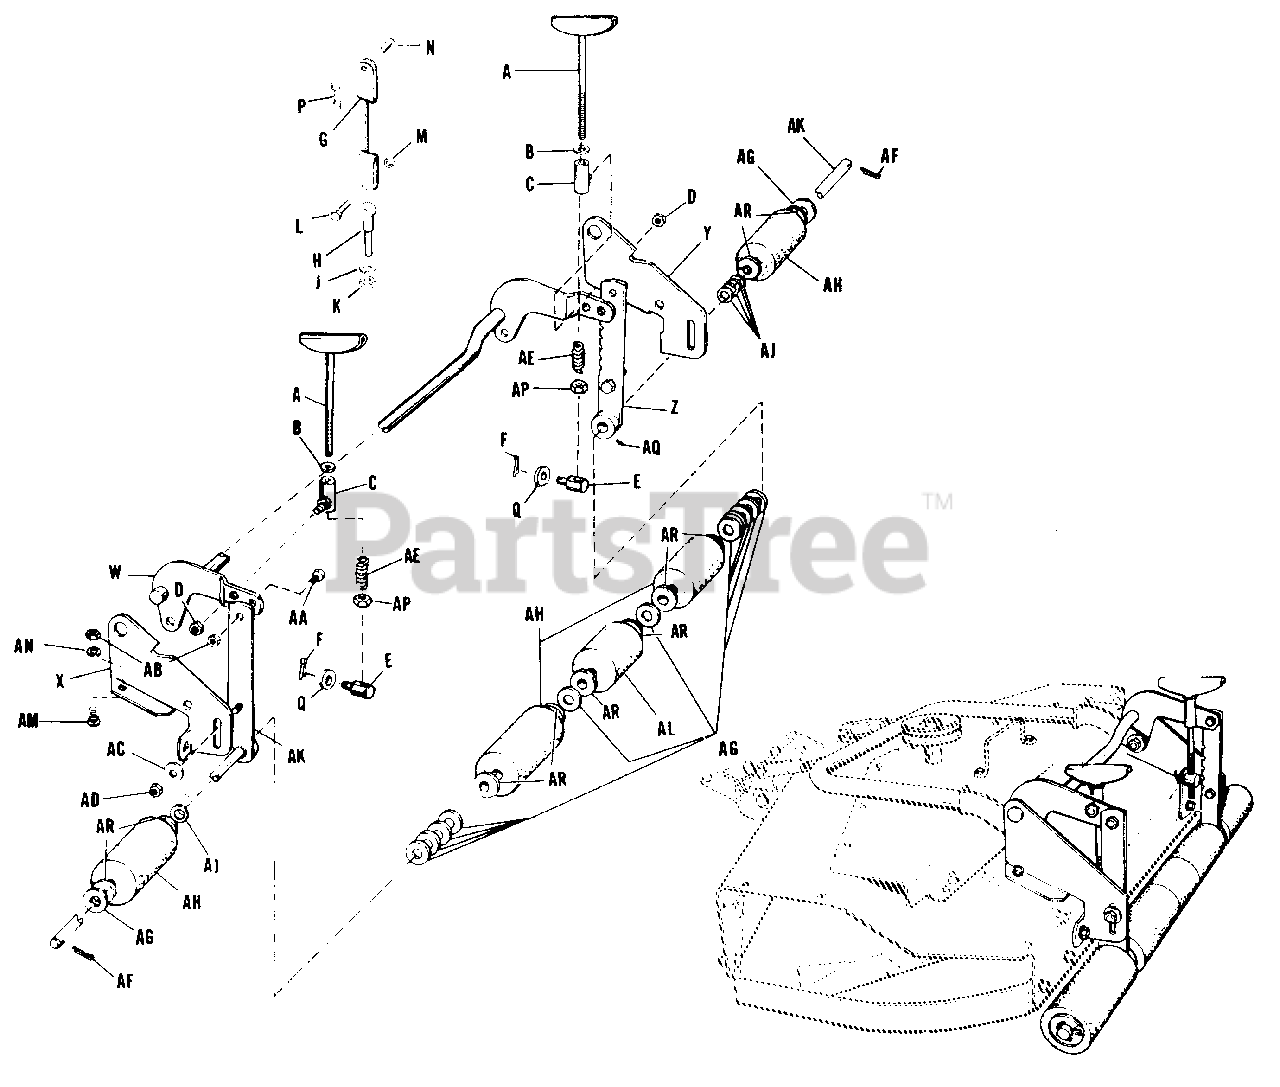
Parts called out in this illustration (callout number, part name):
A	Screw Assembly Adjusting
B	Washer, Plain 3/8 "
C	Socket Assembly, Crank
D	Nut Hex, Full, Lock, 3/8"-16 NC
F	Cotter Pin, 3/32" x 3/4" lg.
G	Cable Assembly, Lift
J	Lock Washer, 3/8" Std.
K	Nut, Hex., Full, 3/8-16 NC
L	Capscrew, Hex Hd., 3/8"-16 x 1" lg.
M	Nut, Hex, Full, Lock, 3/8"-16 NC
P	Clip, Spring
Q	Washer, Plain, 3/8" Std.
W	Arm Assembly, Rocker
X	Bracket, Roller, R.H.
Y	Bracket, Roller, L.H.
Z	Bar Assembly, Roller
AA	Capscrew, Hex Hd., 3/8"-16 NC x 1" lg.
AB	Nut, Hex, Full, 3/8"-16 NC
AC	Washer, Plain 3/8"
AD	Nut, Hex, Full, Lock, 3/8"-16 NC
AE	Spring, Adj. Screw
AF	Pin, Cotter, 3/16" x 1" lg.
AH	Roller W/Bushing
AK	Shaft & Support Arm.
AL	Roller W/Bushing
AM	Bolt, Carriage, 3/8"-16 NC x 3/4" lg.
AN	Washer, Lock, 3/8"
AP	Nut, Hex, Full 3/8"-16 NC
AQ	Set Screw 1/4"-20 NC x 5/16" lg.
